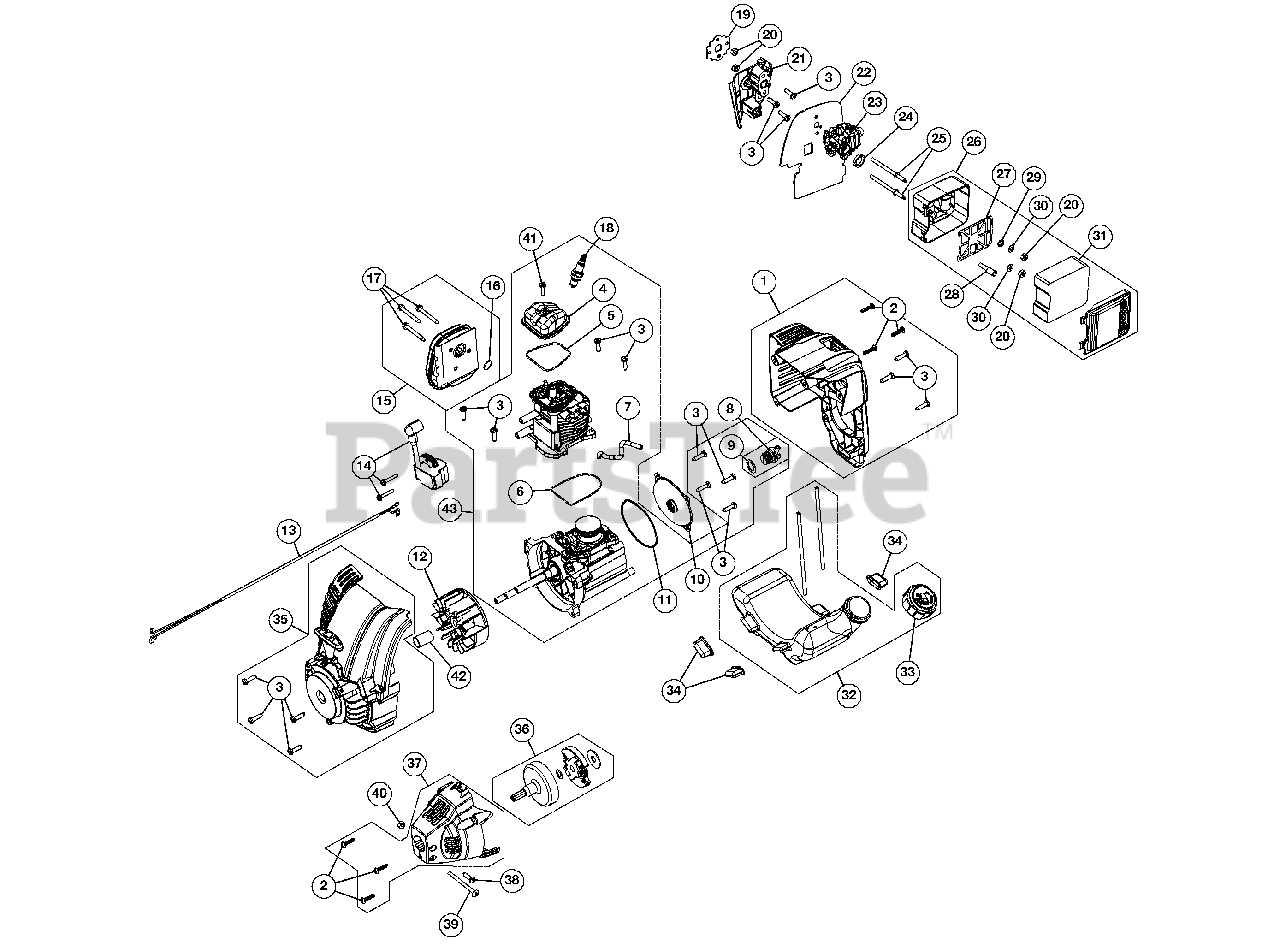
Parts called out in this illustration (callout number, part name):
1	Engine Cover Assembly (Incl. 2 & 3)
2	Cover Screw
3	Starter Screw
4	Rocker Cover
5	Rocker Cover O-Ring
6	Cylinder O-Ring
7	Breather Hose
8	Oil Plug (Incl. 9)
9	Oil Plug O-Ring
10	Crankcase Cover
11	Crankcase Cover O-ring
12	Flywheel Assembly
13	Lead Wires
14	Module Assembly
15	Muffler Assembly (Incl. 16 & 17)
16	Muffler Gasket
17	Muffler Screw
18	Spark Plug
19	Insulator Gasket
22	Carburetor Gasket
23	Carburetor w/Primer
24	Carburetor O-Ring
25	Air Filter Mounting Screw
26	Air Cleaner Cover Assembly (Incl. 27-31)
27	Air Filter Plate
28	Breather Tube Assembly
29	Air Cleaner O-Ring
31	Air Filter
32	Fuel Tank Assembly w/Fuel Lines (Incl. 34)
34	Fuel Tank Pads
35	Starter Housing Assembly (Incl. 3)
36	Clutch Assembly
37	Clutch Cover (Incl. 2)
38	Anti-Rotation Screw
39	Clamp Screw
41	Rocker Cover Screw
43	Shortblock Assembly
